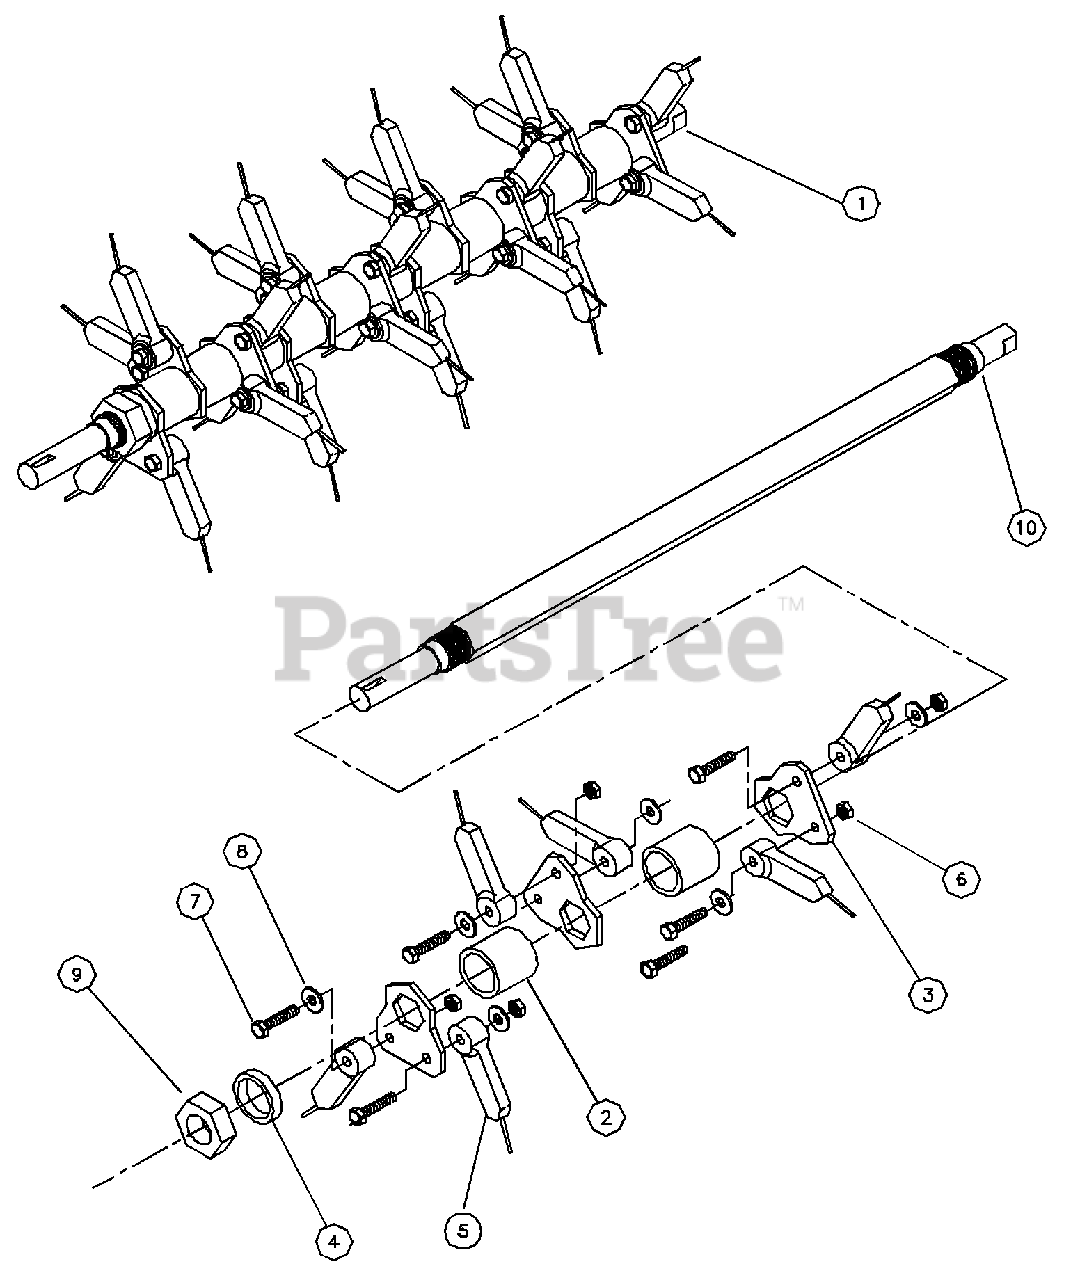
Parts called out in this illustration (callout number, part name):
1	Complete Rake Shaft
2	Spacer, Long
3	Plate, Spring Tine
4	Spacer, Short
5	Spring, Tine
6	1/4c Hex Locknut
7	1/4 x 1-1/4 Hex Bolt
8	1/4" Flat Washer
9	Jam Nut W/Setscrews
10	Shaft, Spring Tine
